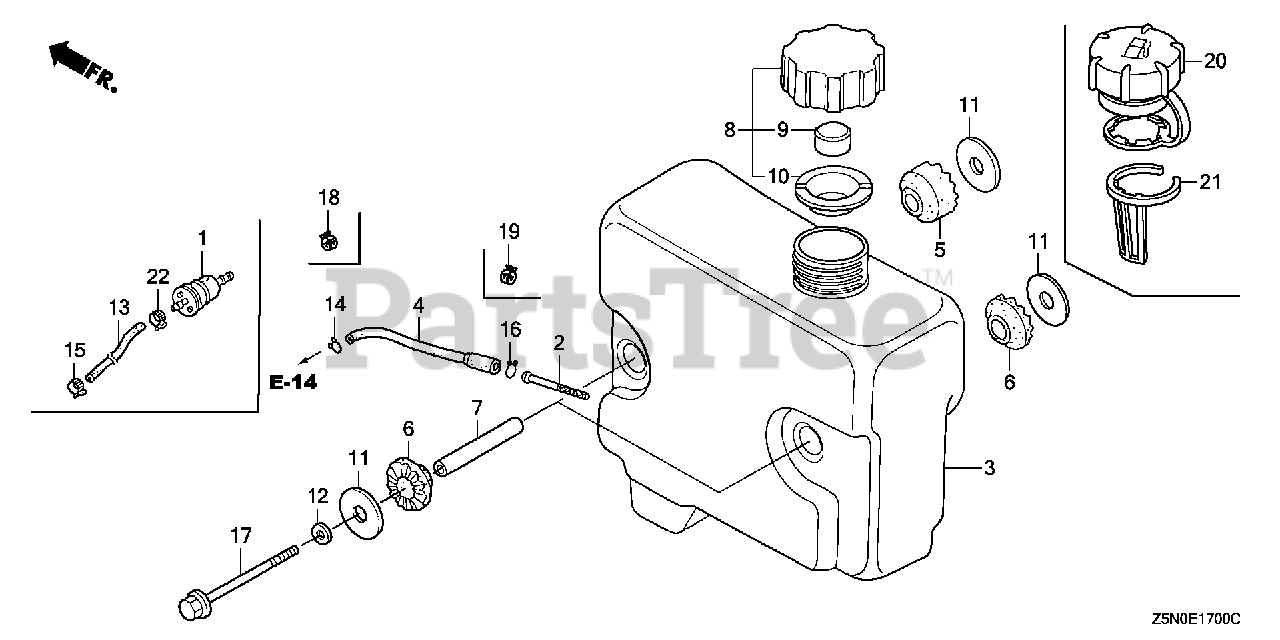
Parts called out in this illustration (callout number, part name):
1	FILTER, FUEL
13	HOSE, FUEL (4.5X360) (FKM)
15	CLAMP, TUBE (D8.5)
22	CLAMP, TUBE (D9.4)
22	CLAMP, TUBE (D8.5)
